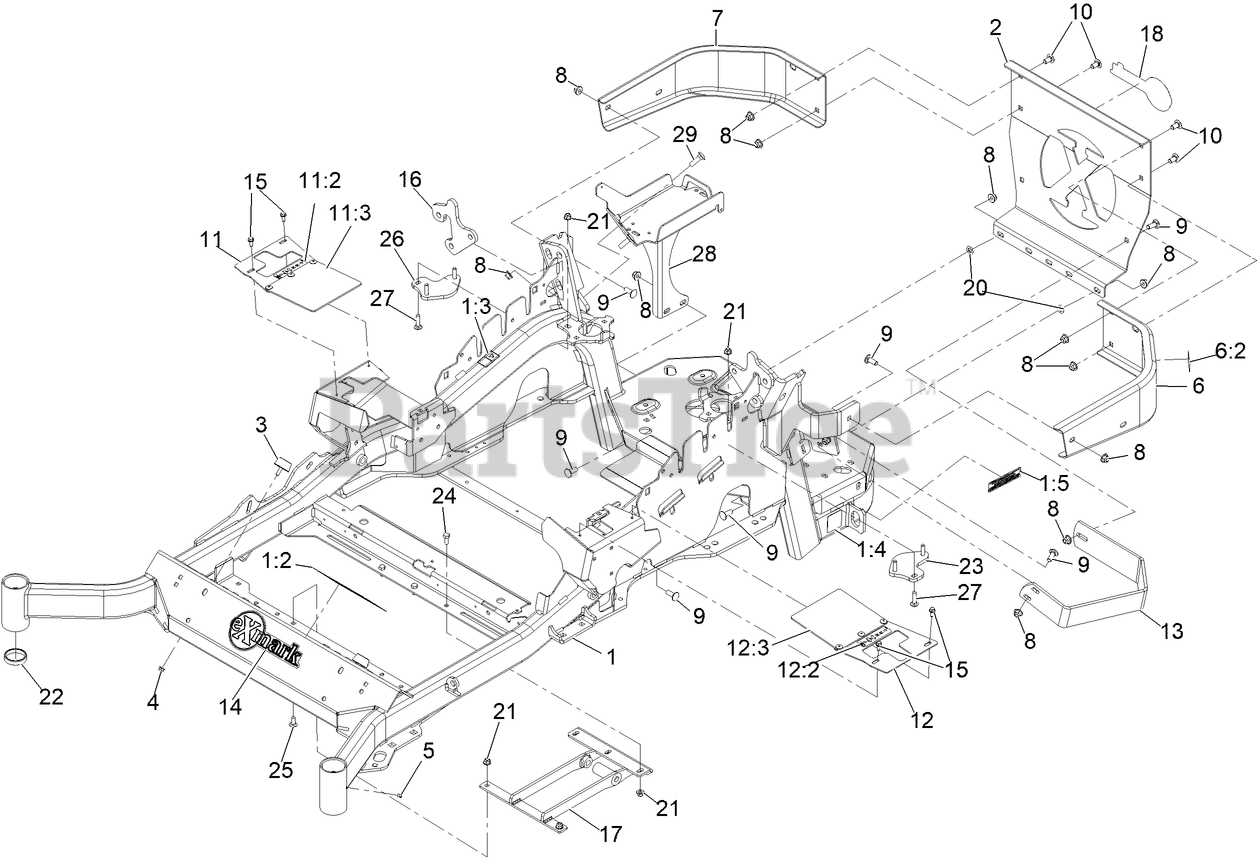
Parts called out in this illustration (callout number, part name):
1	MAINFRAME SERVICE ASM - 60
1:2	DECAL-DANGER
1:3	DECAL-WARNING
1:4	DECAL-HAZARD, PINCHED FINGER
1:5	DECAL-ARRESTOR, SPARK
2	PLATE,REAR GUARD
6	LH BUMPER ASM
6:2	DECAL-WARNING
7	BUMPER-RH
8	NUT-HF, NI
9	SCREW-CARR
10	SCREW-CARR
11	RH MOTION CONTROL COVER A
11:2	DECAL-CONTROL, MOTION
11:3	FLAP-RUBBER
12	LH MOTION CONTROL COVER A
12:2	DECAL-CONTROL, MOTION
12:3	FLAP-RUBBER
13	GUARD-MUFFLER
14	DECAL-EXMARK
15	SCREW-HWH
16	PLATE-MOUNT, SHOCK
17	MOUNT-LOWER
18	DECAL, EXMARK LOGO
20	NUT-PUSH
21	NUT-HF, NI
22	CUP-BEARING
23	LH PLATE ASM (W/STUDS)
24	SCREW-HH
25	SCREW-CARR
26	RH PLATE ASM (W/STUDS)
27	Bolt-Carriage 5/16-18 X 1 1/4
28	BATTERY MOUNT ASM
29	BOLT-CARR
